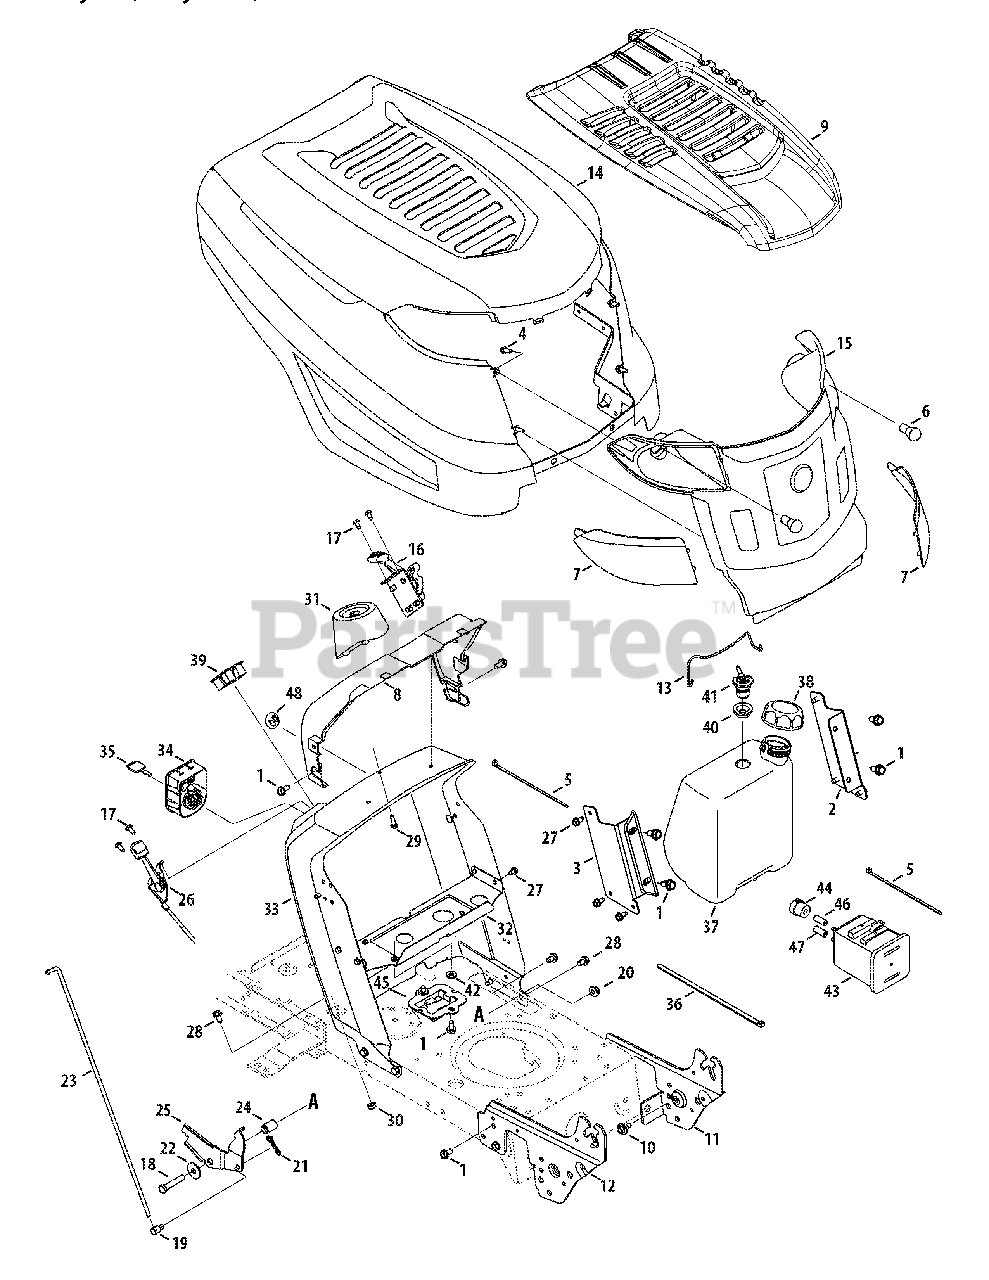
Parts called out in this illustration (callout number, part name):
1	Screw 5/16-18 x .750
2	Fuel Tank Mnt. Bracket - LH
3	Fuel Tank Mnt. Bracket - RH
4	Screw, 1/4 x .750
5	Cable Tie
6	Miniature lamp 12V socket
7	Grill Lens - LH
7	Grill Lens - RH
8	Dash Collar Assembly
9	Hood Scoop
10	Shoulder Screw .43 x .29
11	Suppport Bracket LH
12	Suppport Bracket RH
14	Hood
16	Hydro Control Assembly
17	Screw 1/4-20 x .500
18	Hex Screw 3/8-16 x 2.00
19	Ferrule Adjust
20	Flange Lock Nut 3/8-16
21	Cotter Pin, Bow Tie
22	Flat Washer .411 x 1.25 x .100
23	Control Rod, Speed Selector
23	Control Rod, Speed
24	Flang Spacer .390 x .671 x 1.095
25	Transmission Speed Latch
26	Throttle/Choke Control Cable
27	Hex Screw Washer 1/4-20 x .500
28	Screw 5/16-18 x .625
29	Hex Screw 1/4-15 x .750
30	Flange lock Nut 5/16-18
31	Support Shaft
32	Gas Tank Support Bracket
33	Dash, RMC/Amp Meter/Choke
34	Key Switch Module
36	Cable Tie
37	Fuel Tank, 2 Gallons
37	Fuel Tank, 1.36 Gallon, CARB
38	Fuel Cap
38	Fuel Cap, CARB
39	Ammeter Monitor Indicator
40	Rubber Grommet
41	Rollover Valve
42	Washer, Flat, .344 x .750 x .120
43	Canister, Carbon, 5 Gallon
44	Filter, Vent, Canister
45	Bracket., Adapter, Canister
46	Hose, Fuel, Low Perm., White
47	Hose, Fuel, Low Perm., Yellow
48	Choke Plug
